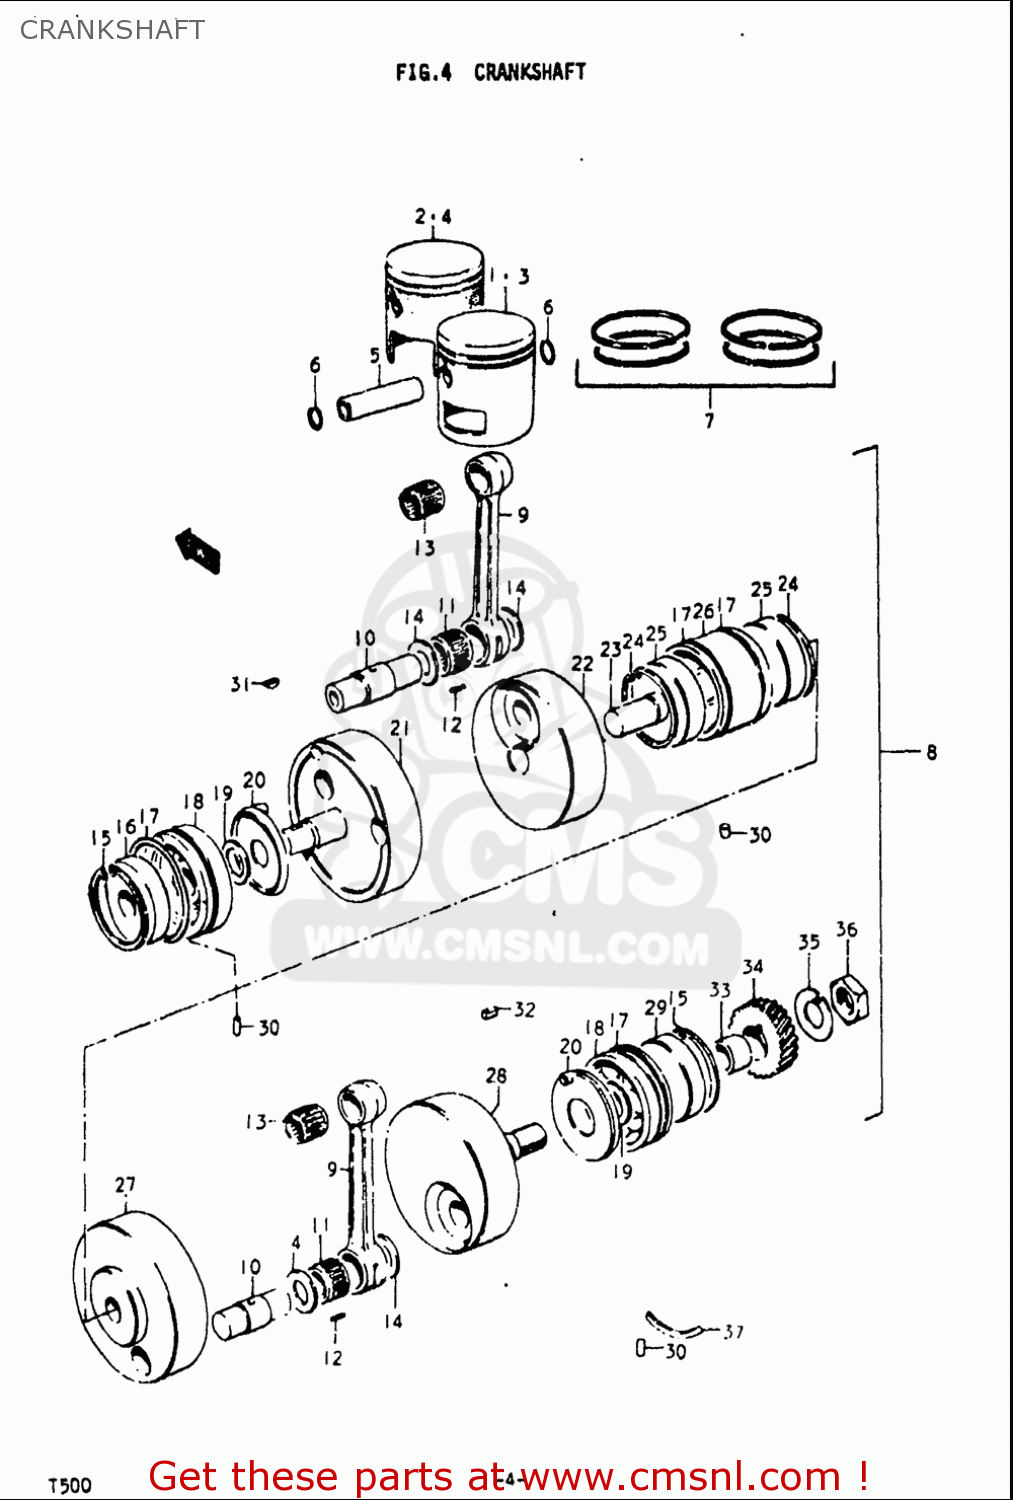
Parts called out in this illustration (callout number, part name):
1	PISTON SET(OS:0.5)
2	PISTON SET(OS:1.0)
3	PISTON,L
4	PISTON SET(OS:0.5)
5	PIN,PISTON (18MM)
6	CIRCLIP,PISTON PIN
7	RING SET,PISTON
10	PIN,CRANK
12	ROLLER
13	BEARING(18X23X24)
16	SEAL,OIL(25X62X8)
17	O RING(D:2.5,ID:68.5)
19	SHIM(25X40X1)
20	PLATE,CRANKSHAFT OIL GUIDE
25	SEAL,OIL(30X65X8)
30	PIN
31	KEY
32	KEY
33	SPACER
36	NUT (20MM)
37	C-RING
